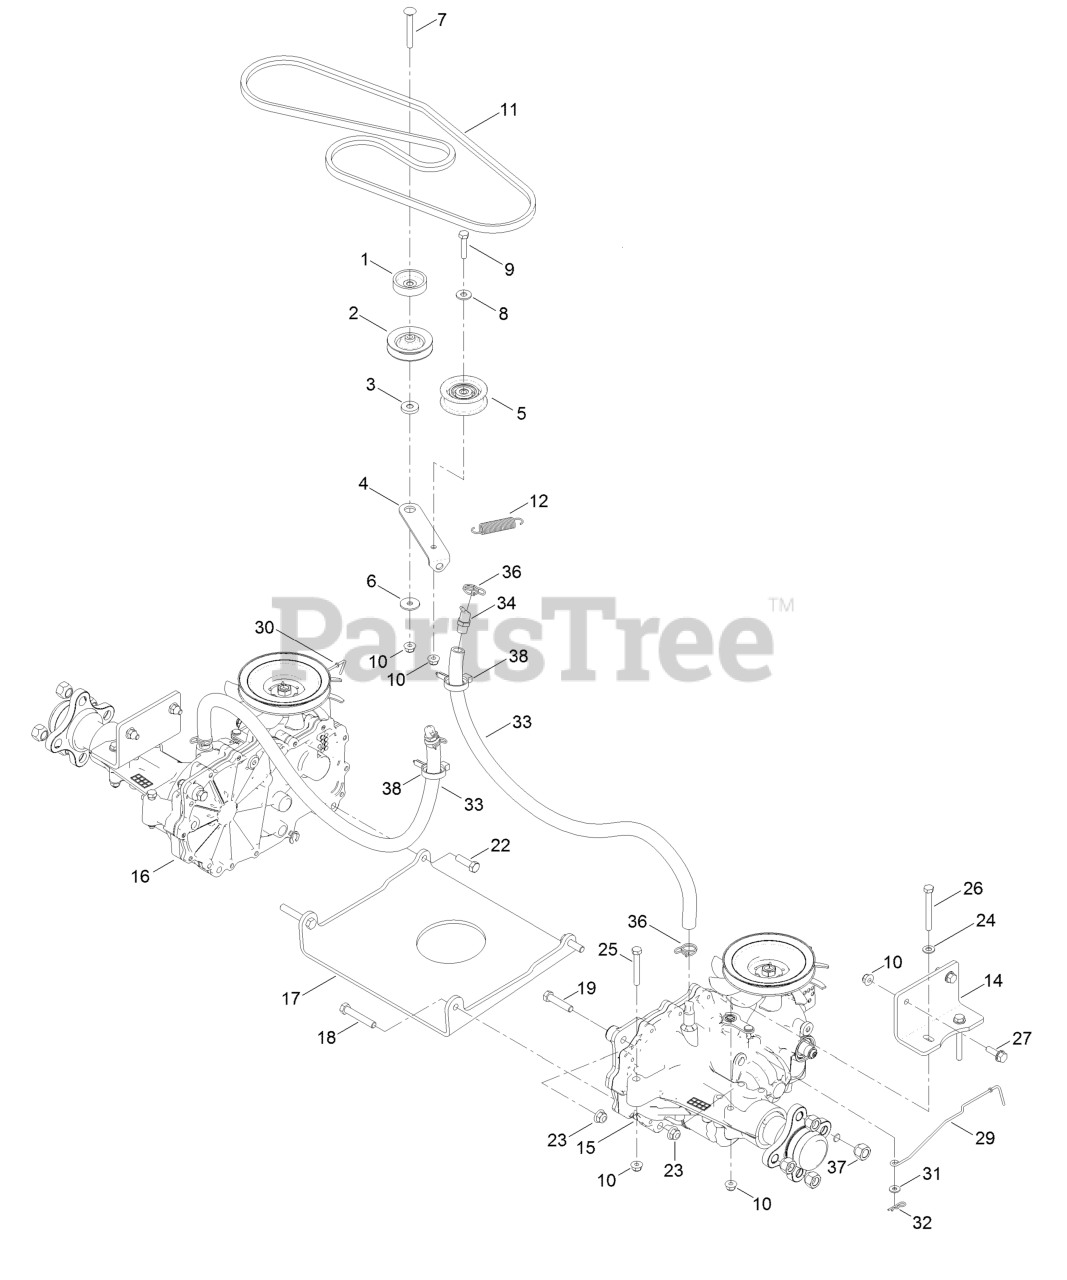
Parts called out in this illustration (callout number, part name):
2	Pulley-Idler
3	Spacer-Arm, Idler
4	Arm-Idler
5	Pulley-Idler
6	Washer-Pivot
7	Screw-CARR
8	Washer-Flat
9	Screw-HH
10	Nut-HF, NI
12	Spring-Return, Pedal
14	Mount-Hydro
15	LH Hydro Transmission ASM
16	RH Hydro Transmission ASM
17	Plate-Cross, Hydro
18	Screw-HH
19	Screw-HH
22	Screw-HH
23	Nut-HF, NI
24	Washer-Plain
25	Screw-HH
26	Screw-HH
27	Screw-HHF
29	Rod-Bypass, LH
30	Rod-Bypass, RH
32	Pin-Cotter
33	Hose-Hydro
34	Breather Kit
36	Clamp-Hose
37	Nut-Lug
38	Clamp-Hose
